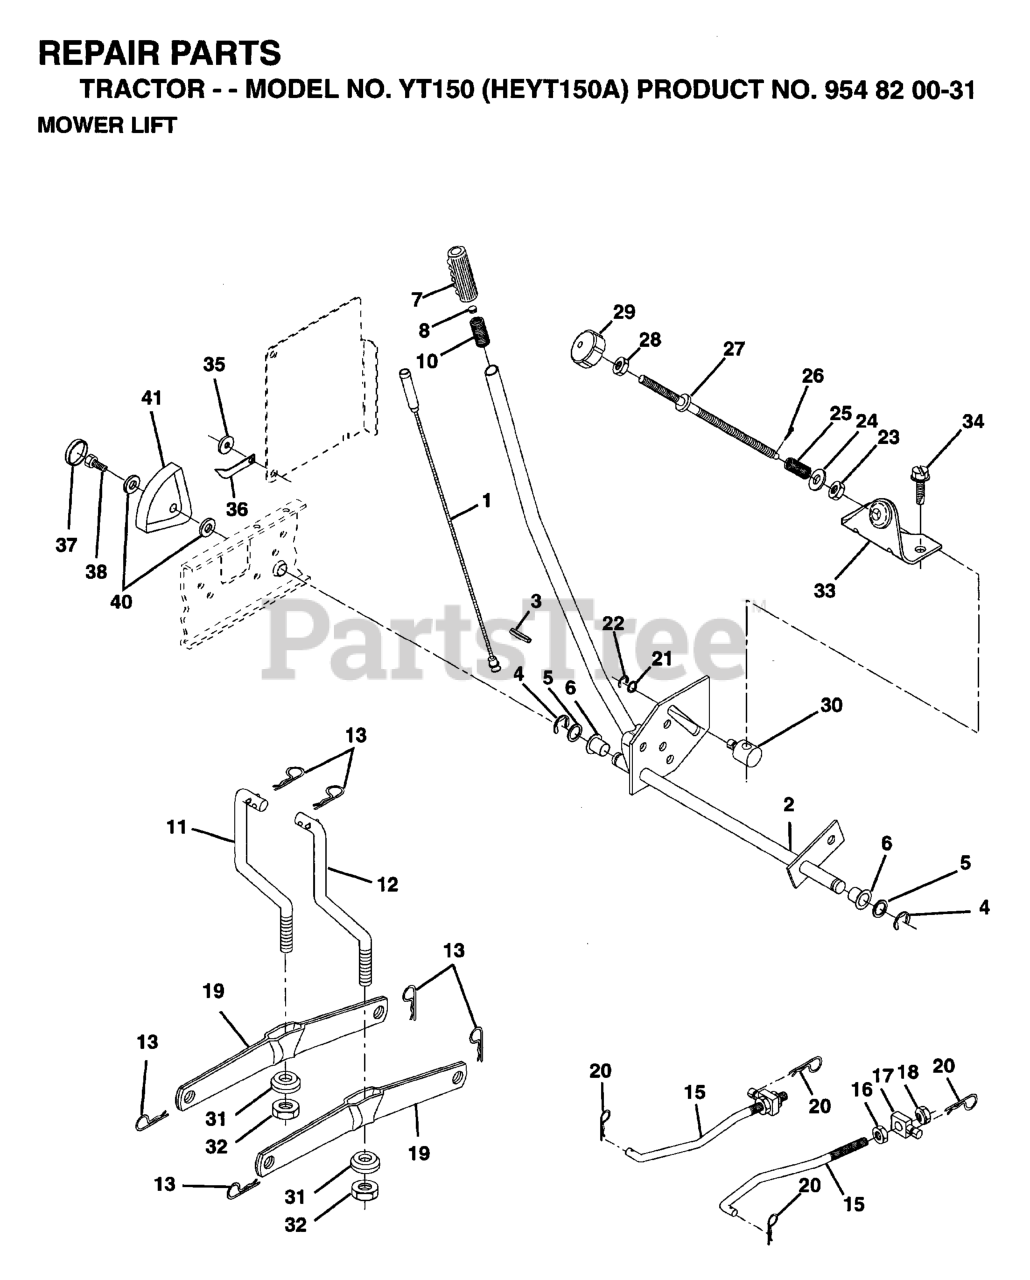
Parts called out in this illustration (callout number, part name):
1	WIRE.INNER.HANDLE.LIFT.LEVER
2	LIFT ARM ASSY
3	PIN GROOVE
4	RETAINING RING LT
6	BEARING.NYLON
7	CAP
8	PLUNGER BUT KIT
10	SPRING, COMP T
11	LINK LIFT LH
12	LINK LIFT RH
13	RETAINER-SPRNG RB
15	FRONT LINK
16	NUT.HEX.JAM.1/2-13
17	TRUNION
18	NUT.LK.W/WSH.1/2.
19	ARM.REAR.SUSPENSION
20	SPRING RETAINER
21	Washer 15/32 x 3/4 x 16 Gauge
22	Ring, Klip #T5304-37
25	SPRING**
26	COTTER PIN
27	ROD ADJ LIFT
28	NUT
29	KNOB INF 3/8-16
30	TRUNION LT
31	BEARING PIVOT
32	NUT CROWNLOCK 3/8-24
36	POINTER HGT
38	SCREW.THDROL.5/16-18X3/4.TTY
41	HEIGHT INDICATOR
